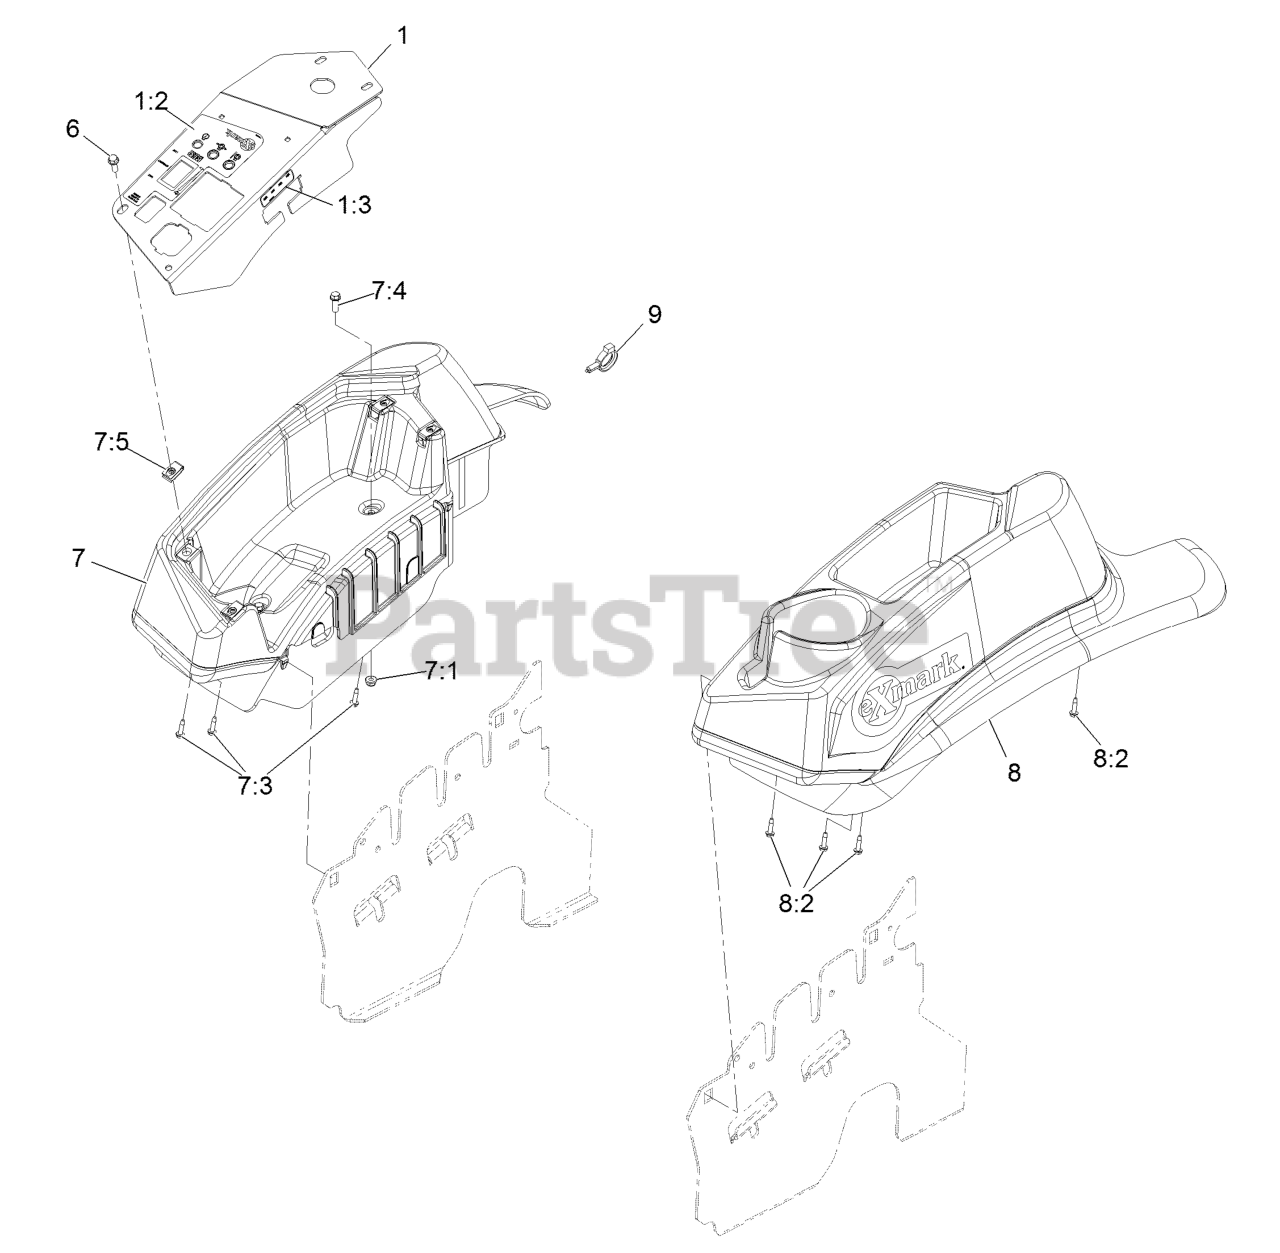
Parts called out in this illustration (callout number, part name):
1	CONTROL PANEL W/DECAL
1:2	Decal-E-Gov Control
1:3	DECAL-FUSE
6	SCREW-HWH
7	CONSOLE,RH NARROW ASM
7:3	SCREW,THD FORM,HWH
7:4	SCREW-HWH
7:5	Nut-Retainer-Panel 1/4-20
8	CONSOLE.LH NARROW ASM
8:2	SCREW,THD FORM,HWH
9	CLAMP-HOSE
